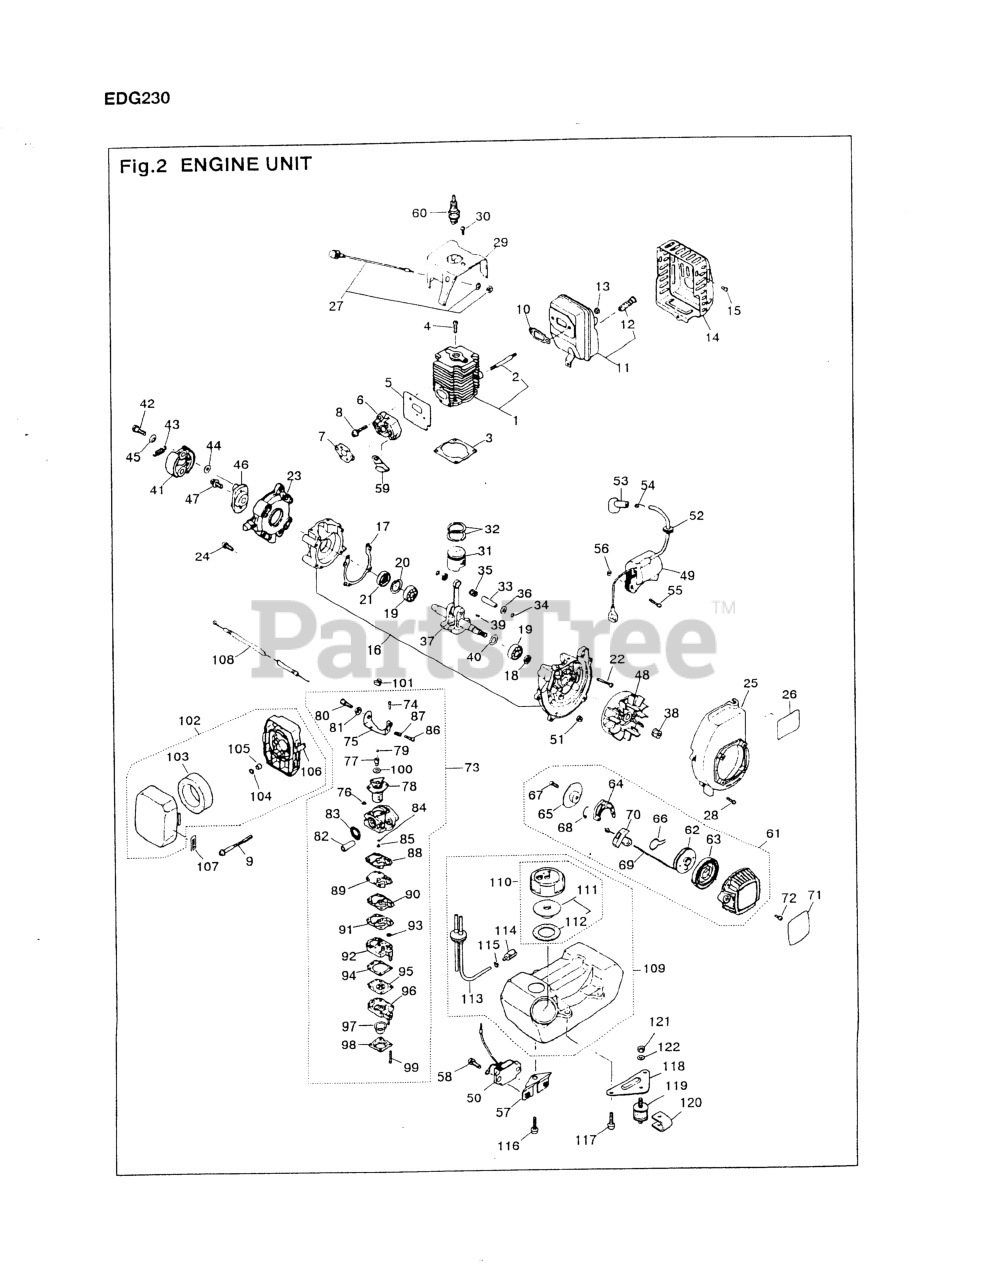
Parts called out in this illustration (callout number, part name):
1	CYLINDER-C
2	STUD
4	SCREW, M5 X 16
6	INSULATOR
11	MUFFLER ASSEMBLY
12	ARRESTER (RPLS 5850-15140)
13	NUT
16	CRANKCASE (RPLS -21100)
18	SEAL, OIL
19	BEARING
20	RING, SNAP, M28 x 1.2
21	SEAL, OIL (RPLS 1140-21220)
22	SCREW, M5 x 30(RPLS 0263-00530
23	CASE, CLUTCH (USE 1140-21162)
25	COVER (REPLACES -31101)
27	SWITCH ASSY (RPLS -72200)
28	SCREW, M4 x 14
29	COVER, CYLINDER
31	PISTON (USE 5600-41111)
33	PIN, PISTON 5x8x26
34	RING, SNAP (RPLS 1101-41320)
36	WASHER
37	CRANKSHAFT
39	KEY
42	BOLT
44	WASHER, FLAT (USE 182303)
47	BOLT, M6 x 14(RPLS 0224-00614)
50	UNIT
54	SPRING
55	SCREW, M4 x 20
56	WASHER, M5 X .8
57	BRACKET (RPLS -72240)
58	SCREW, M5 X 12
59	CLAMP
61	STARTER ASSEMBLY
64	RATCHET
65	PLATE (NLA) (RPLS -75240)
66	SPRING, FRICTION
67	SCREW (REPLACES -75260)
68	SPRING
70	KNOB
72	SCREW, M4 X 12
73	CARBURETOR-A (NLA)
74	SCREW
75	BRACKET, IDLE
76	RING
77	SWIVEL (USE -06040)
78	VALVE, THROTTLE
79	PLUG NEEDLE
81	NUT, CABLE ADJUSTER
82	SLEEVE, MOUNT
83	RING, PACKING (NLA)
84	RING, O
86	SCREW, IDLE AD
87	SPRING, IDLE A
88	GASKET, PUMP
89	DIAPHRAGM
90	PLATE, PUMP (NLA)
91	GASKET, PLATE
92	KIT ONLY
93	SCREEN
94	KIT ONLY
95	DIAPHRAGM (USE 4810-81260)
96	BODY
97	PUMP, PRIMING
98	COVER
99	SCREW
100	WASHER
101	CAP, CABLE END
102	CLEANER ASSEMBLY
105	SLEEVE (USE 1918-82170)
107	LABEL
108	CABLE
111	VALVE COMPLETE
112	PACKING (RPLS -85321)
114	5500-85400 (RRLS. 1750-85300)
115	CLIP (REPLACES 2841-31280)
118	PLATE (USE 5635-87112)
119	JOINT
120	BAND
121	NUT, M5 X 4
122	WASHER, SPRING M4 x 1.3
